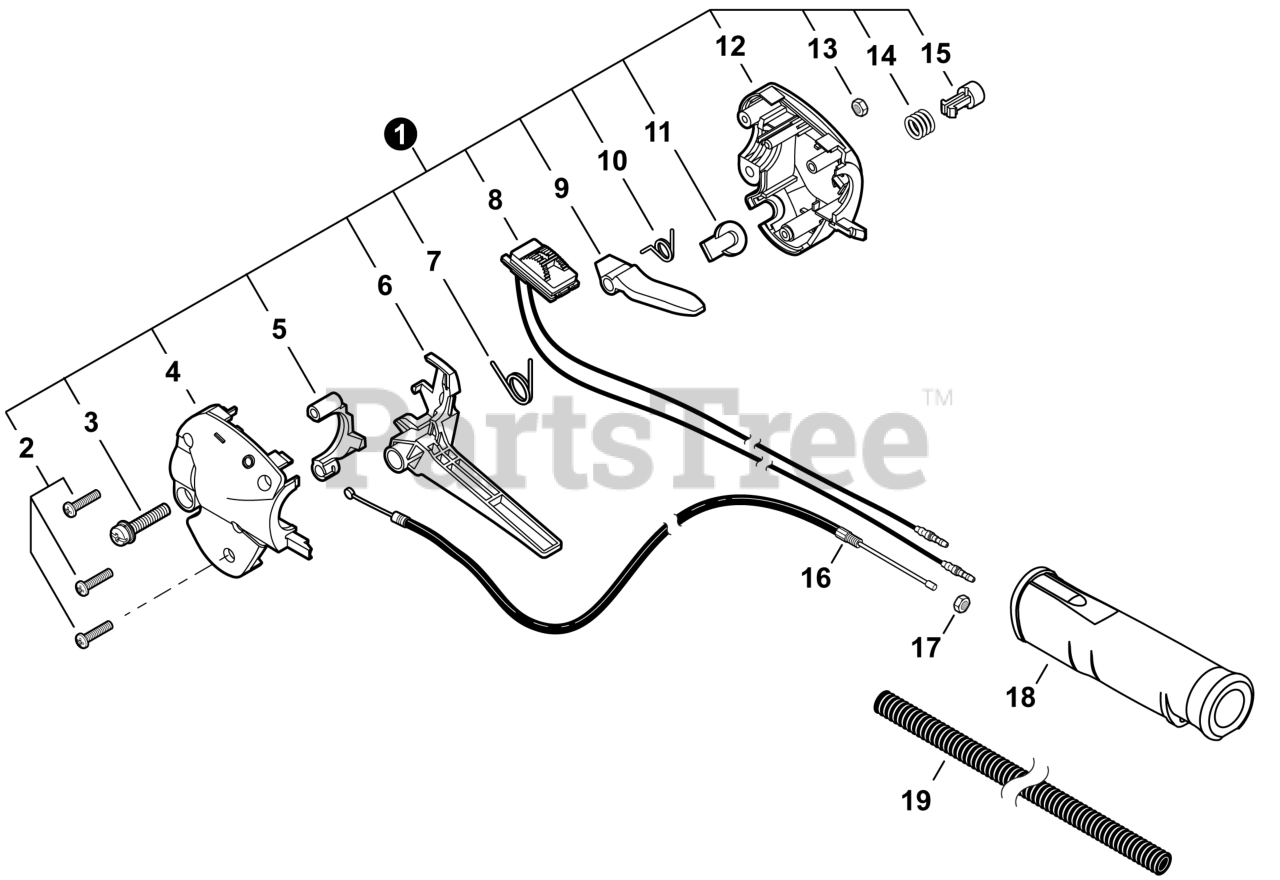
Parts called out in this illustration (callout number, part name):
1	THROTTLE CONTROL ASSY
2	SCREW, TAPPING M4×20
3	SCREW M5×20
4	CONTROL HANDLE - LEFT
5	LOCKOUT, THROTTLE
6	TRIGGER, THROTTLE
7	SPRING, THROTTLE RETURN
8	SWITCH, ON-OFF
9	LEVER, THROTTLE LOCKOUT
10	SPRING, THROTTLE LOCKOUT
12	CONTROL HANDLE - RIGHT
14	SPRING, COMPRESSION
15	BUTTON, THROTTLE LOCK
16	CABLE, THROTTLE
18	GRIP, HANDLE
19	TUBE, PLASTIC PROTECTIVE
